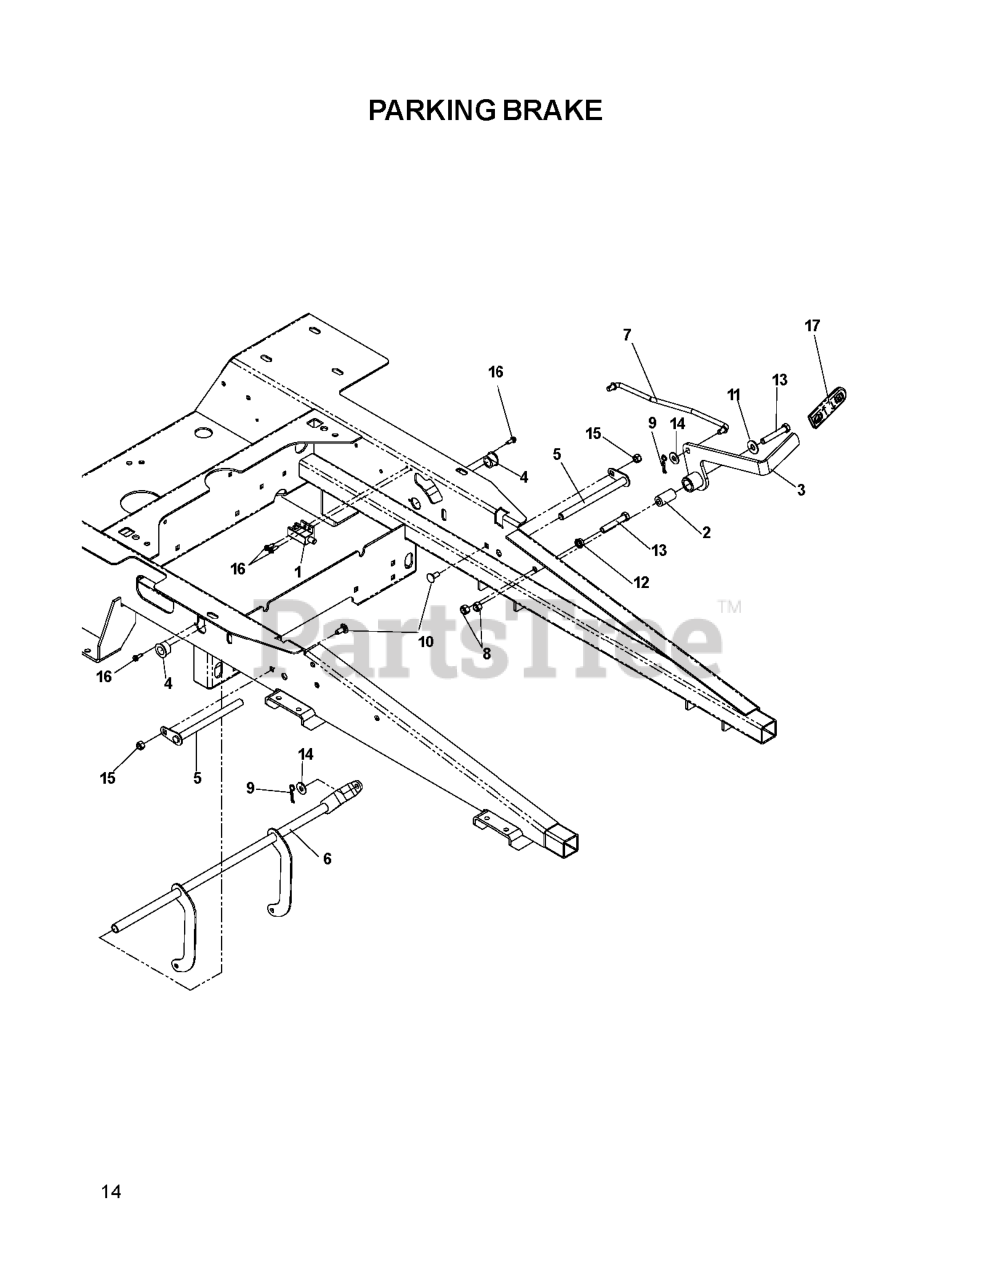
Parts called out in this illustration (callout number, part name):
1	SWITCH, BRAKE 3P
2	BUSHING, SLEEVE
3	BRAKE LEVER WLDMT
4	PLASTIC BUSHING
5	PIVOT SHAFT
6	BRAKE SHAFT
7	BRAKE LINKAGE
8	NUT 3/8-16 NYLOC
9	HAIRPIN #2
10	BOLT 5/16C X 3/4" CARRIAGE
11	WASHER 3/8 FLAT
12	NUT 3/8C WHIZ
13	HCS 3/8C X 2 1/4
14	WASHER 5/16 FLAT
15	NUT 5/16 NYLOC
16	SCREW #10 X 1/2 SELF TAPPING
17	GRIP, PARK BRAKE
